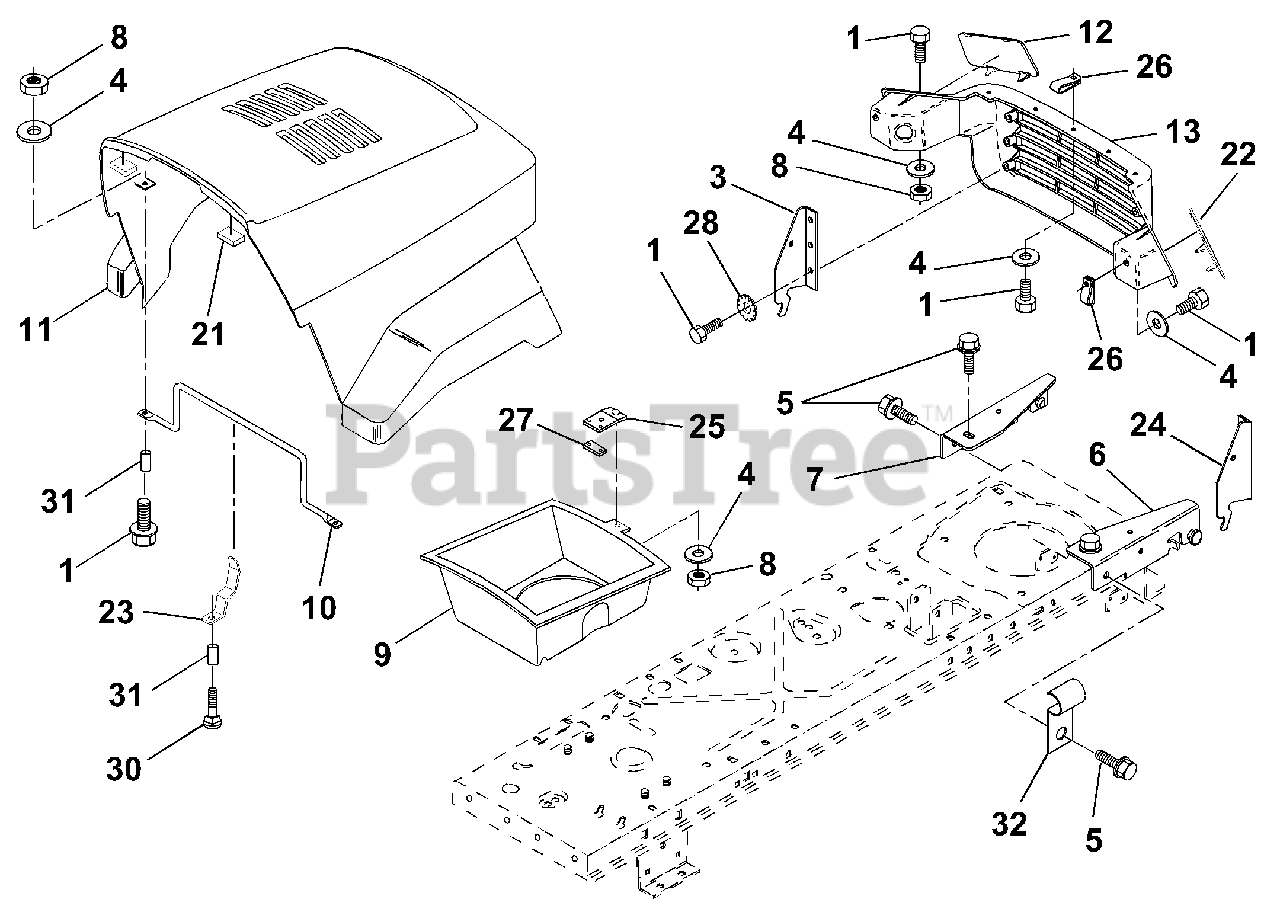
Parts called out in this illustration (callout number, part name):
1	Bolt Fin Hex 1/4-20 x 5/8
3	Bracket Pivot Hood LH
4	Washer 9/32 x 3/4 x 16 Ga.
5	Screw Thdrol 5/16-18 x 3/4
6	Bracket Asm. Pivot Hood RH
7	Bracket Asm. Pivot Hood LH
8	Nut Keps 1/4-20
9	Duct Air Hood
10	Brace Hood
13	Grille
21	Bumper Hood
23	Latch Hood
24	Bracket Pivot Hood RH
25	Clip Asm. Duct Air
26	Clip Tinnerman
27	Clip Tinnerman
28	Washer Lock Ext Tooth
30	Bolt RDHD Sht Nk 1/4 - 20 x 1-3/8
31	Spacer
32	Clip Line Fuel
